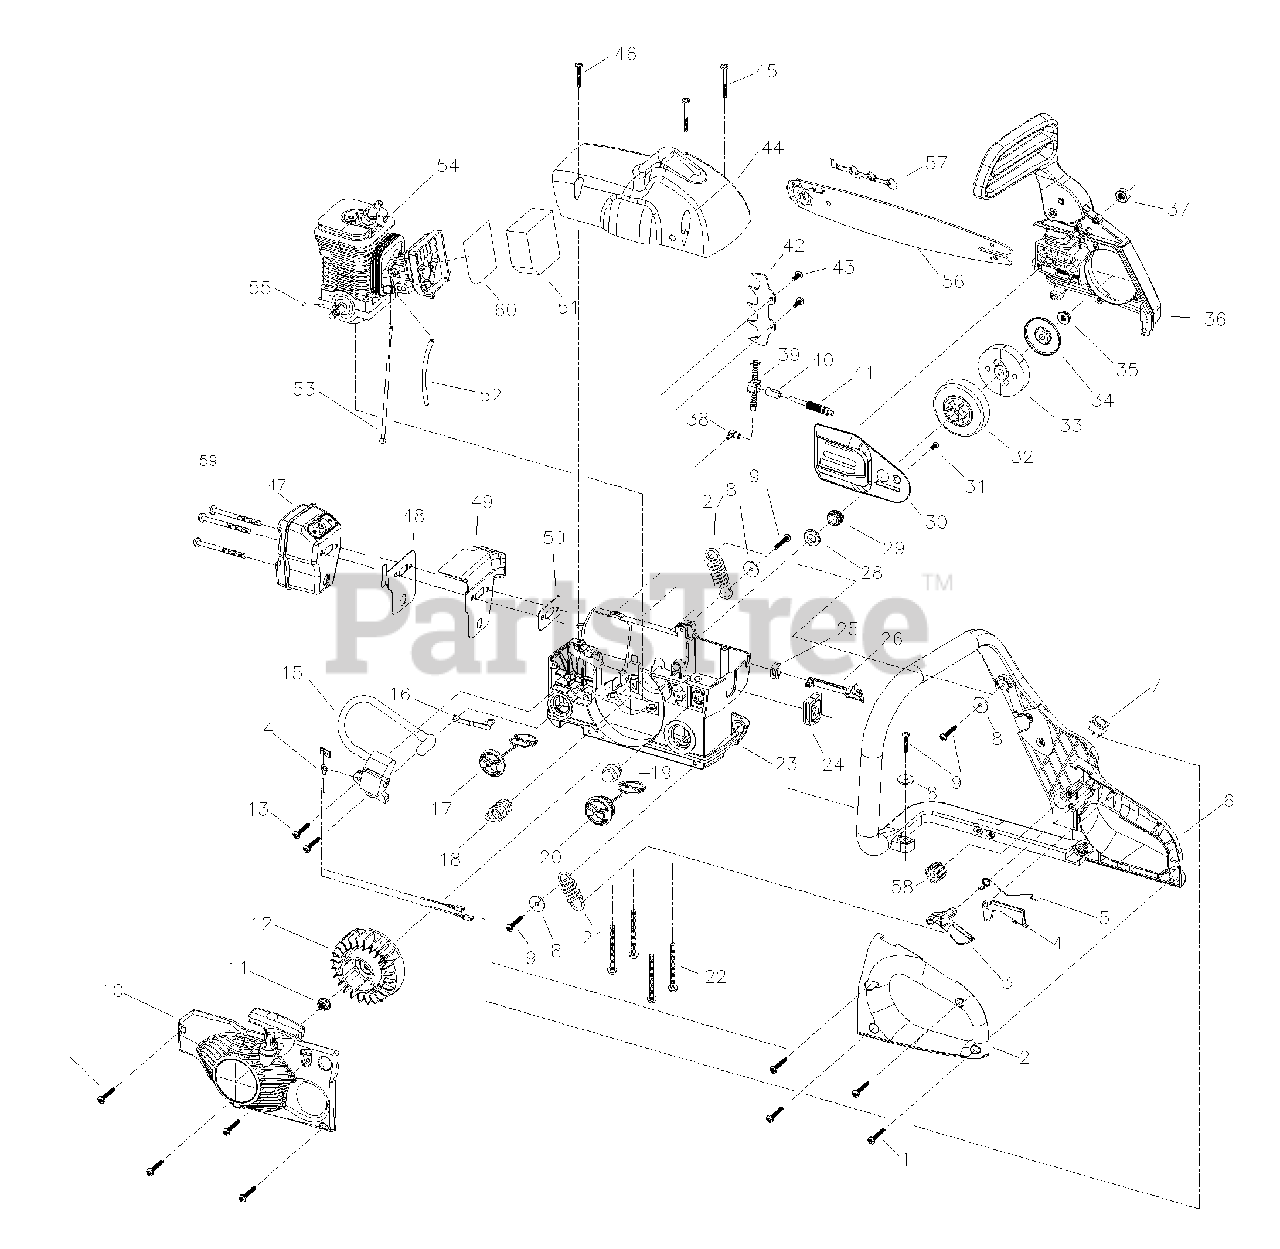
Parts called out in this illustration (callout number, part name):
2	HANDLE, LEFT PART
3	TRIGGER, THROTTLE
4	TRIGGER, RELEASE
6	HANDLE, REAR ASS'Y
10	STARTER HOUSING ASS'Y
14	WIRE ASS'Y
15	IGNITION ASS'Y
16	CONDUCTIVE PLATE
17	OIL CAP ASS'Y
18	SPRING ASS'Y
20	FUEL CAP ASS'Y
23	HOUSING ASS'Y
24	HOLDER, CABLE
25	HOLDER, CHOKE LEVEL
26	LEVER, CHOKE
30	CAP, ONTI-DUST
32	DRUM ASS'Y
33	CLUTCH ASS'Y
34	CAP, ANTI-DUST
36	BRAKE KIT ASS'Y
38	CONNECTOR
40	BUSHING, PUMP
41	SHAFT, PUMP
42	SPIKED BUMPER
46	SCREW
47	MUFFLER ASS'Y
51	FILTER, AIR
52	FUEL PIPE
53	CABLE, THROTTLE
54	ENGINE ASS'Y
55	WOODRUFF KEY
